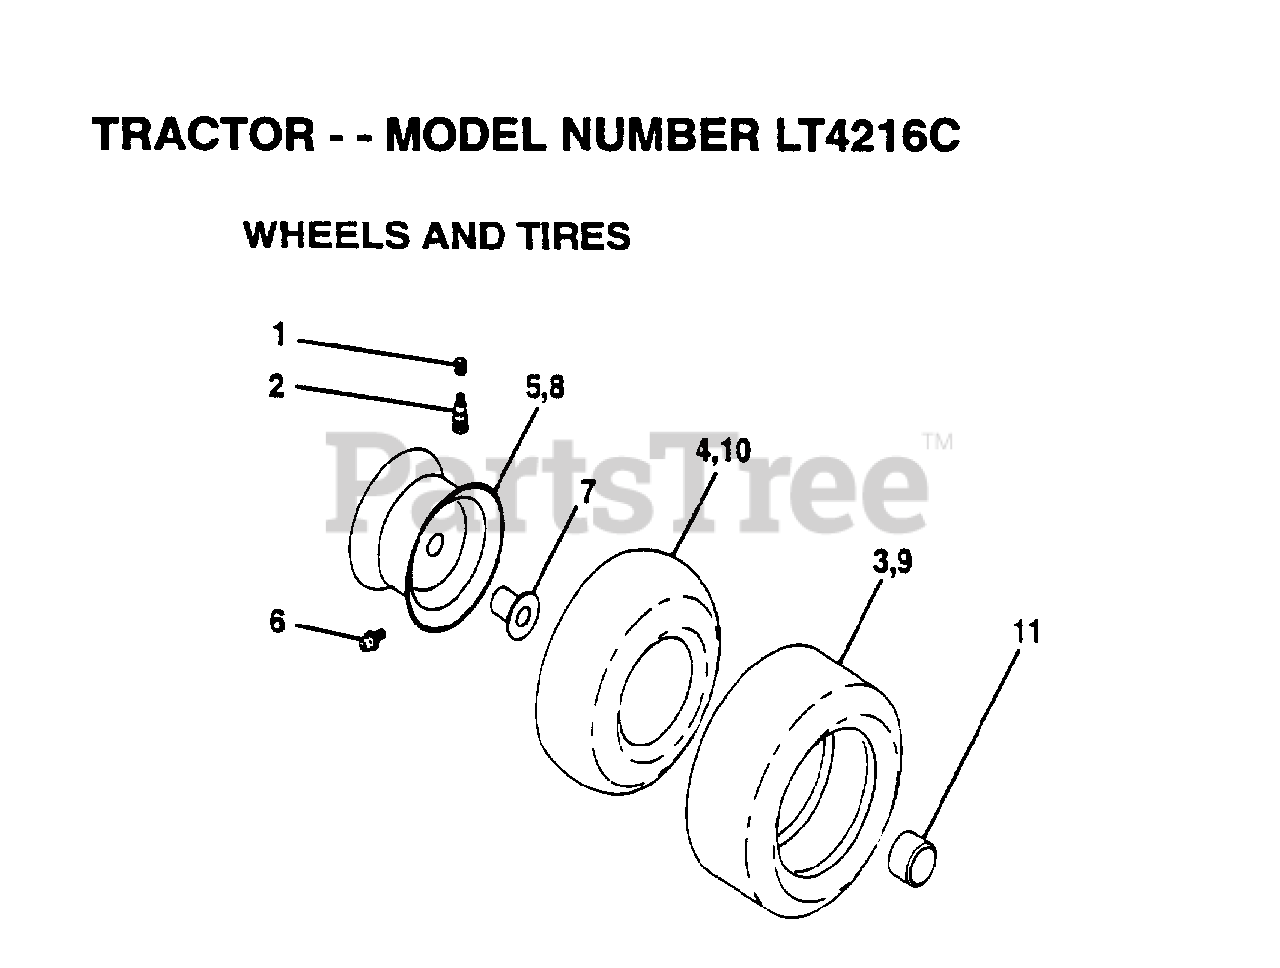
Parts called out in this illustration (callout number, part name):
1	VALVE CAP
2	VALVE STEM LT
4	TUBE.5.3/4.5/6
5	"RIM FRT 6"" ASM"
6	FITTING LT
7	"FLANGE, BEARING"
8	"RIM REAR 8"" ASM"
9	TIRE.20X8-8
10	TUBE.18X9.5-8
11	HUB CAP
